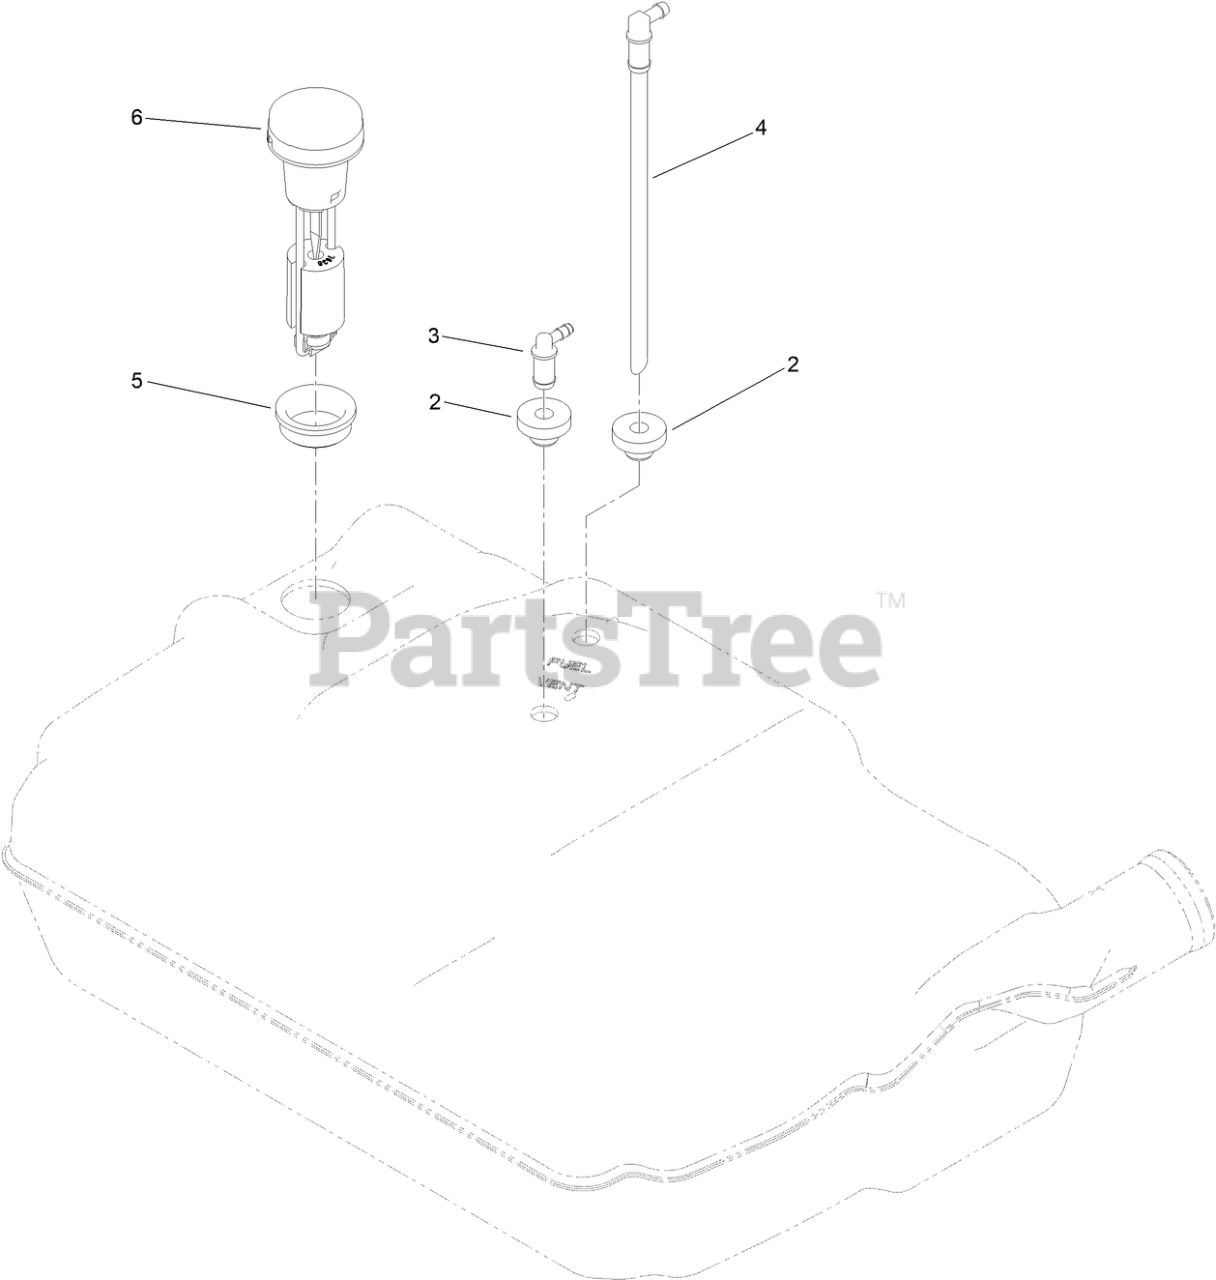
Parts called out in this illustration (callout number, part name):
2	BUSHING
3	FITTING-ELBOW 90
4	FITTING - PICKUP, FUEL
5	GROMMET-FUEL
6	REMOTE GAUGE ASM
